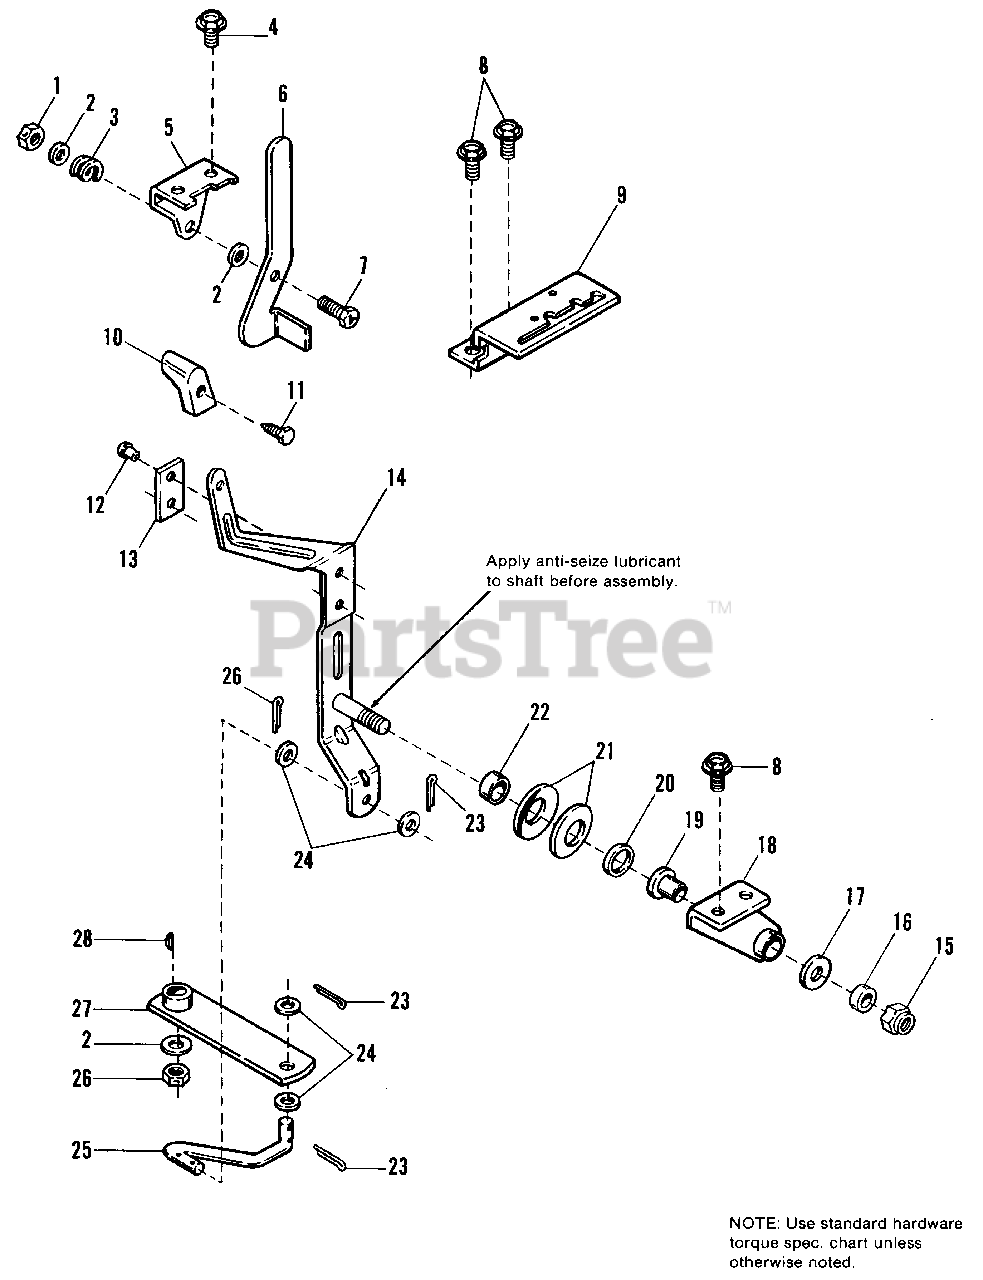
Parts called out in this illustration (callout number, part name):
1	NUT, Hex, Lock, 5/16-18
2	WASHER, Plain, 5/16
3	WASHER, Spring, Double, 3/8
4	SCREW, Taptite, 1/4-20 x 1/2
5	SUPPORT, Handle, Release Valve
6	HANDLE, Release Valve
7	CAPSCREW, Hex, 5/16-18 x 1-1/4
8	SCREW, Taptite, 5/16-18 x 3/4
11	SCREW, Taptite, 1/4-20 x 1
13	PLATE, Wear
14	LEVER ASSY., Control
15	NUT, Hex, Lock, 5/8-11
18	SUPPORT ASSY. Control
20	WASHER, Special
21	WASHER, Spring
23	PIN, Cotter
24	WASHER, Plain, 13/32 x 7/8
25	LINK, Control
26	NUT, Hex, Lock, 3/8-16
27	ARM ASSY., Control
28	KEY, Woodruff, #3, 1/8 x 1/2
